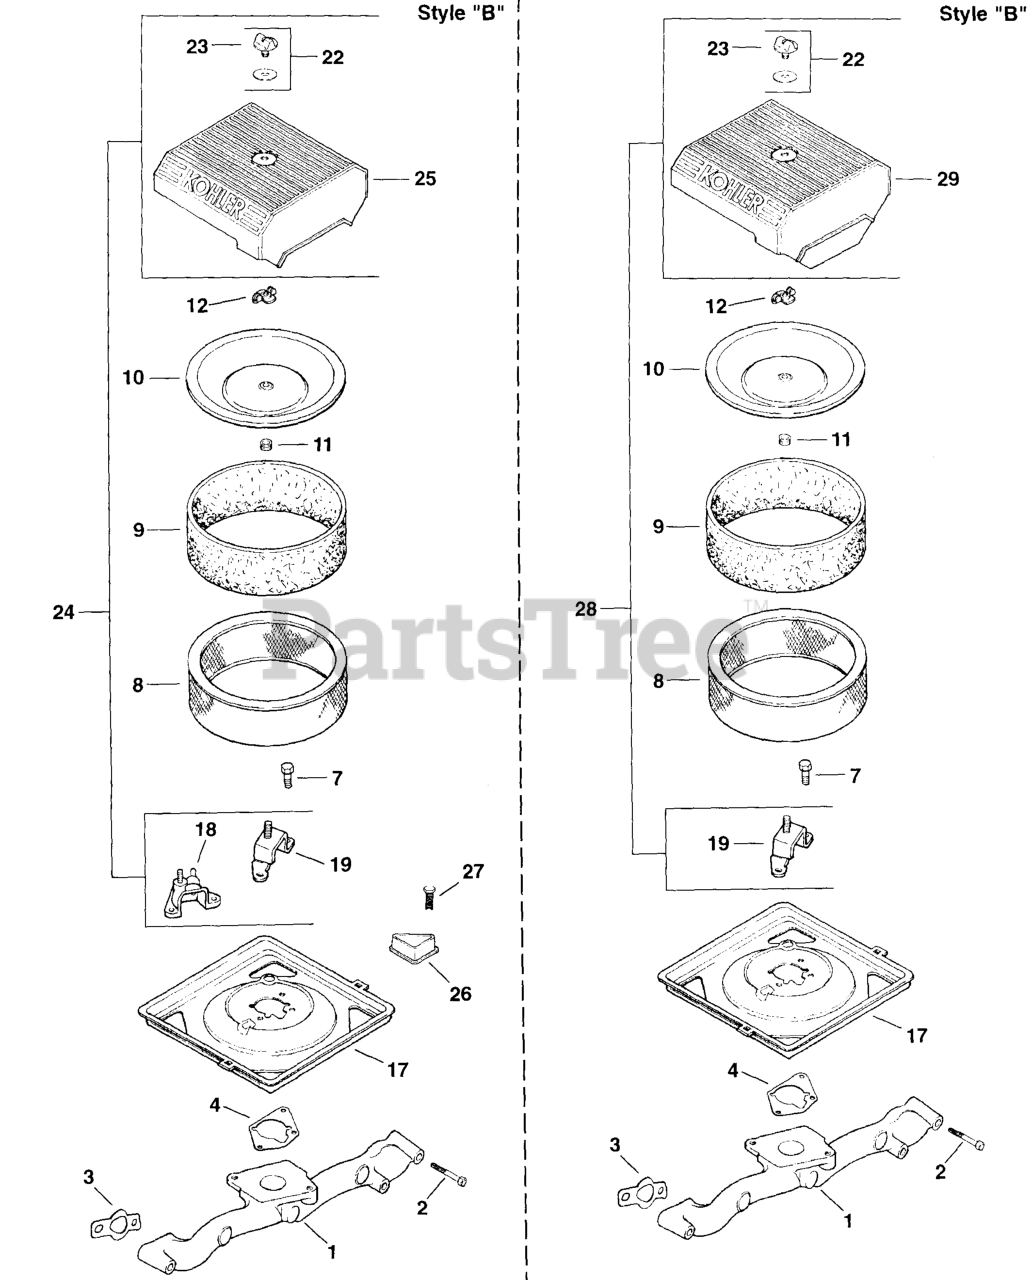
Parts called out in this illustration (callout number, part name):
1	MANIFOLD, METAL INTAKE
2	Screw, hex. flange M6x1.0x55
3	GASKET, INTAKE MANIFOLD USE 24 041 79-S
4	GASKET, AIR CLEANER BASE
7	SCREW - USE M-645016
8	ELEMENT, AIR FILTER (HIGH) - Also available Retail Packaged 24 883 03-S1 Air Filter Kit
9	PRE-CLEANER (HIGH)
10	COVER, INNER AIR CLEANER
11	SEAL, BREATHER
12	NUT, WING
18	KIT - USE 24 755 86
22	KIT - USE 54 755 01
23	KNOB - USE 25 341 03
24	KIT, AIR CLEANER COVER
25	COVER, AIR CLEANER
26	COVER, BLOWER HOUSING USE 24 096 160-S
27	SCREW, WSH HD TAP #8-18X1/2" USE 25 086 91-S
